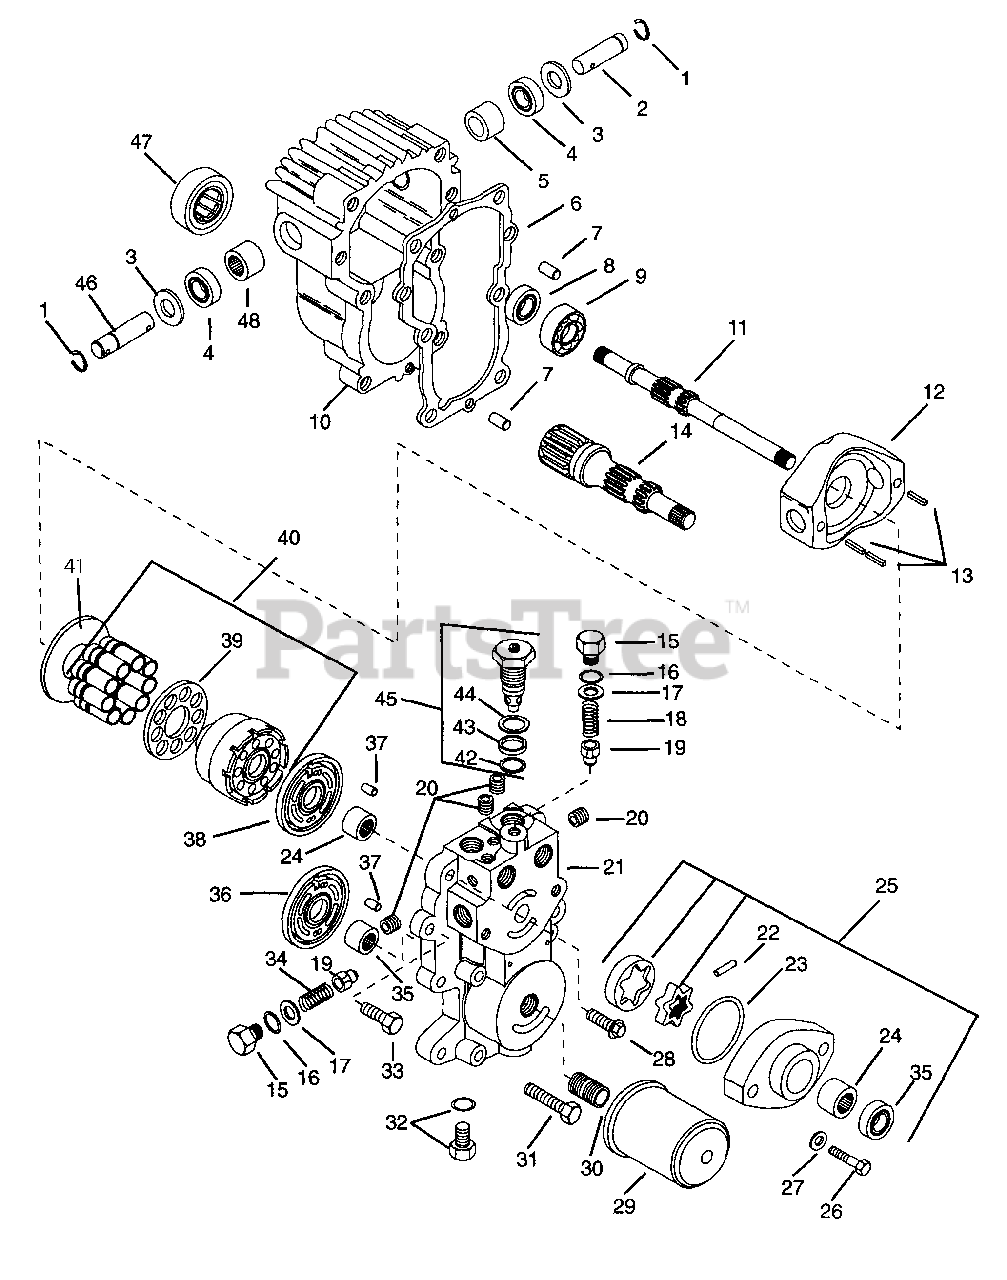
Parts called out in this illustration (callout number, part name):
1	Ring-Retaining-External .688 x .042
2	Trunnion Shaft
3	Washer-Flat-Steel .699 x 1.375 x .059
4	Seal .625 x 1.187 x .187
5	Journal Bearing
7	Dowel Pin
8	Seal 1.987 x 1.500 x .313
9	Bearing, Ball
10	Housing Assembly Kit
11	Shaft, Pump
12	Swashplate Variable
13	Pin-Roll .188 x .63
14	Shaft, Motor
15	Plug-Hex Head
16	O-Ring .414 x .562 x .072
17	Shim Package
18	Spring-Compression
19	Relief Valve Cone
20	Pipe Plug
21	Center Section
23	O-Ring 2.364 x 2.504 x .072
24	Bearing, Needle
25	Charge Pump Assembly Kit
26	Bolt-Hex .44-14 x 2.00 Grade 5
27	Washer-Flat-Steel .469 x .719 x .108
28	Screw-12 Point .38-16 x 1.25 Grade 5
29	Oil Filter
31	Bolt-Hex .38-16 x 2.00 Grade 5
32	Threaded Plug
33	Bolt-Hex .38-16 x 1.50 Grade 5
34	Spring-Compression
35	Seal 1.987 x 1.375 x .313
36	Motor Valve Plate
37	Dowel Pin
38	Valve Plate
39	Slipper Retainer
40	Cylinder Block Kit
41	Thrust Plate
42	O-Ring .614 x .750 x .070
43	O-Ring .614 x .750 x .046
44	O-Ring .770 x .968 x .097
45	Check Valve Assembly Kit
46	Trunnion Shaft
48	Needle Bearing
